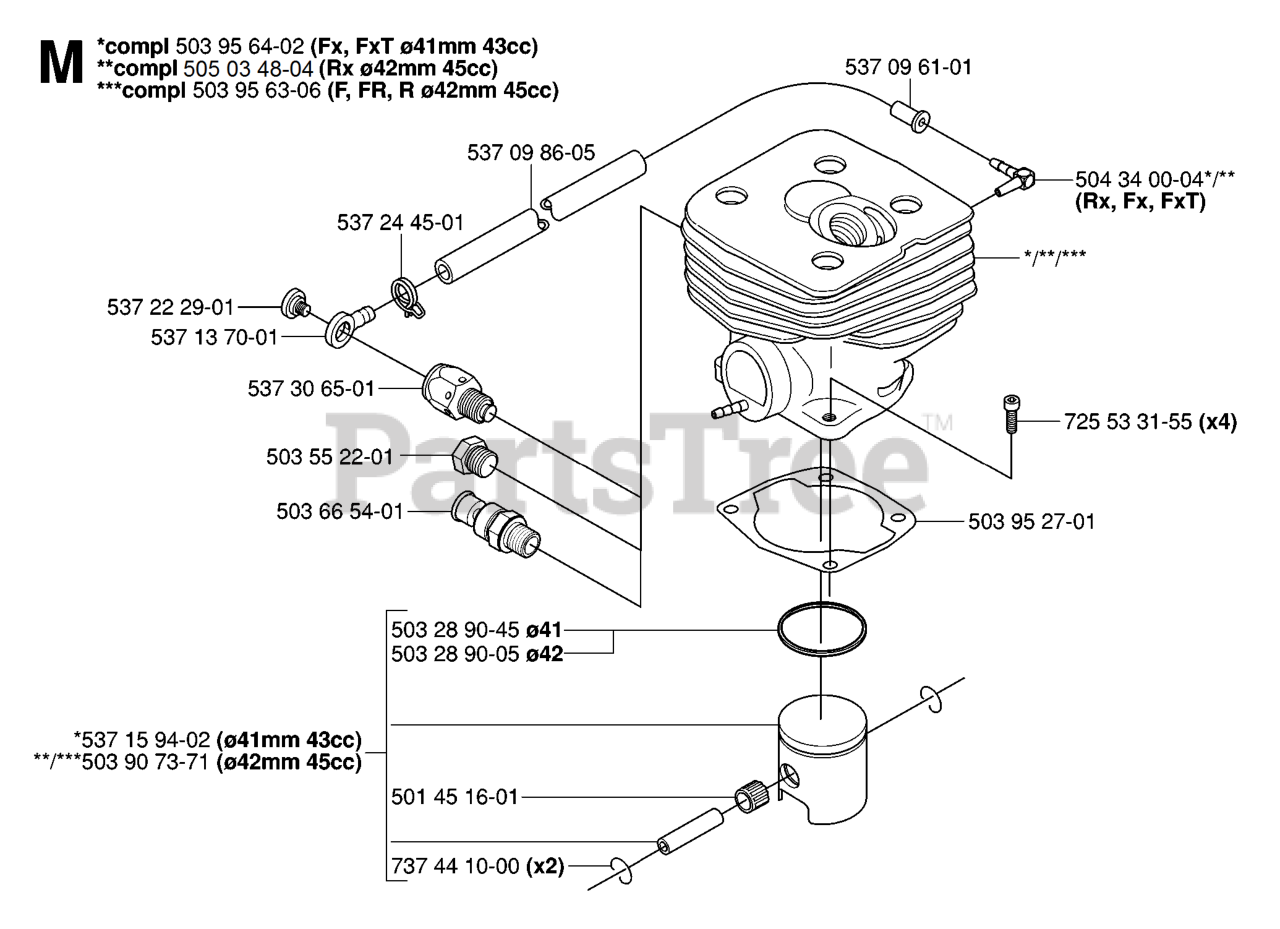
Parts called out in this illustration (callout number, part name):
1	ROD.ASM.IMPELLER
2	ROD.ASM.TRACTION
3	ROD, UPPER SPEED CONTROL
4	ROD, LOWER SPEED CONTROL.SNOW
5	SLEEVE, SPRING
6	SPRING, AUGER CONTROL
7	SPRING, TRACTION DRIVE
8	BOLT
9	NUT.FLANGE.5/16
10	SPRING RETAINER
11	ROD.CLUTCH.YELLOW.ZINC(VT)
12	PLATE.REAR.SNOW.PNT.ORANGE
13	BRACKET.SHIFTER.PLATE.BZP
14	BRACKET.CLUTCH.PLATE.BZP
15	PLATE.CLUTCH.BZP
16	PLATE.SHIFTER.BZP
17	SELF-TAPPING SCREW 5/16-18X3/4
18	BOLT.SHOULDER.3/X.25
19	NUT.HEX.FLANGE.1/4
